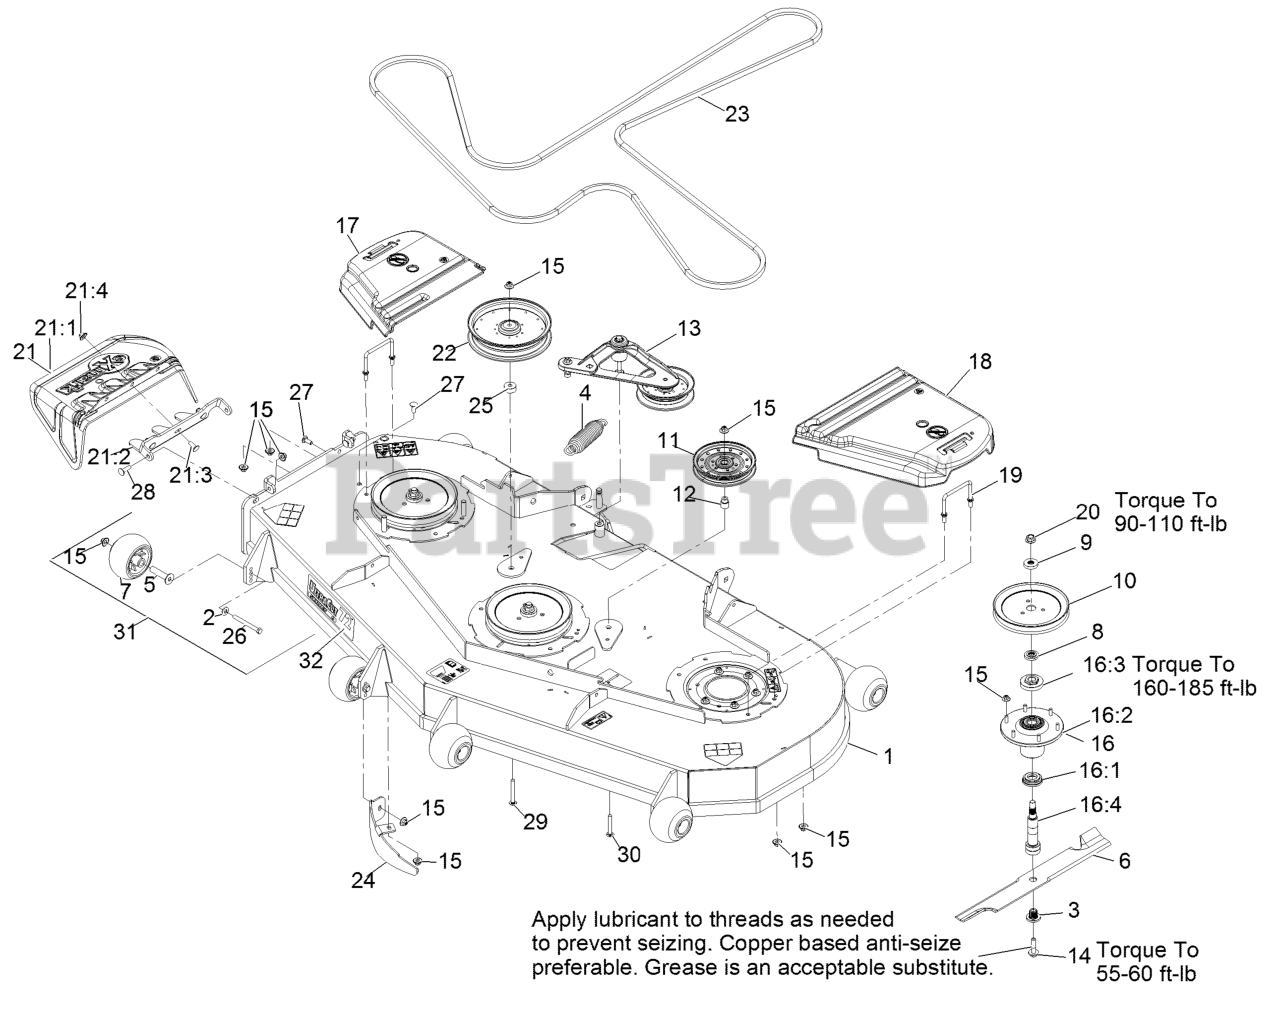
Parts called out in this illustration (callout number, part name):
1	DECK W/ DECALS ASM-72
2	WASHER-BELLEVILLE
3	BUSHING,SPLINED
4	SPRING-EXTENSION
5	AXLE, ROLLER
7	ROLLER-SCALP, ANTI
8	SPACER,SPLINED STEPPED
9	SPACER,SPLINED
10	SHEAVE,BLADE DRIVE 9.00
12	BUSHING-IDLER
13	DECK IDLER ASM
14	SCREW,SEMS 1/2-20 X 2.19
15	Nut-Nyloc 3/8-16 Flg
16	ASM,SPINDLE HOUSING
16:1	GUARD,BOTTOM
16:2	ASM,CUTTER HOUSING
16:3	NUT, SPINDLE 7/8-14
16:4	SPINDLE,DOUBLE SPLINE
17	COVER-BELT, RH
18	COVER-BELT, LH
19	WIREFORM-COVER
20	NUT-FLANGE, CENTERLOCK
21	ASM,DISCHARGE CHUTE
21:1	CHUTE,DISCHARGE
21:2	BRACKET,DISCHARGE CHUTE
21:3	SCREW-CARR
21:4	Nut-Nyloc 3/8-16 Flg
22	PULLEY-IDLER
23	BELT-V
24	BAFFLE-DOGLEG, LZ72
25	SPACER-IDLER
26	SCREW-HH 3/8-16 X 3 3/4 GR 8
27	SCREW-CARR
28	Bolt-Carriage 3/8-16 X 1 1/4
29	SCREW-CARR
30	SCREW-CARR
31	KIT, ANTI-SCALP ROLLER
32	DECAL,ULTRACUT 72 SERIES
